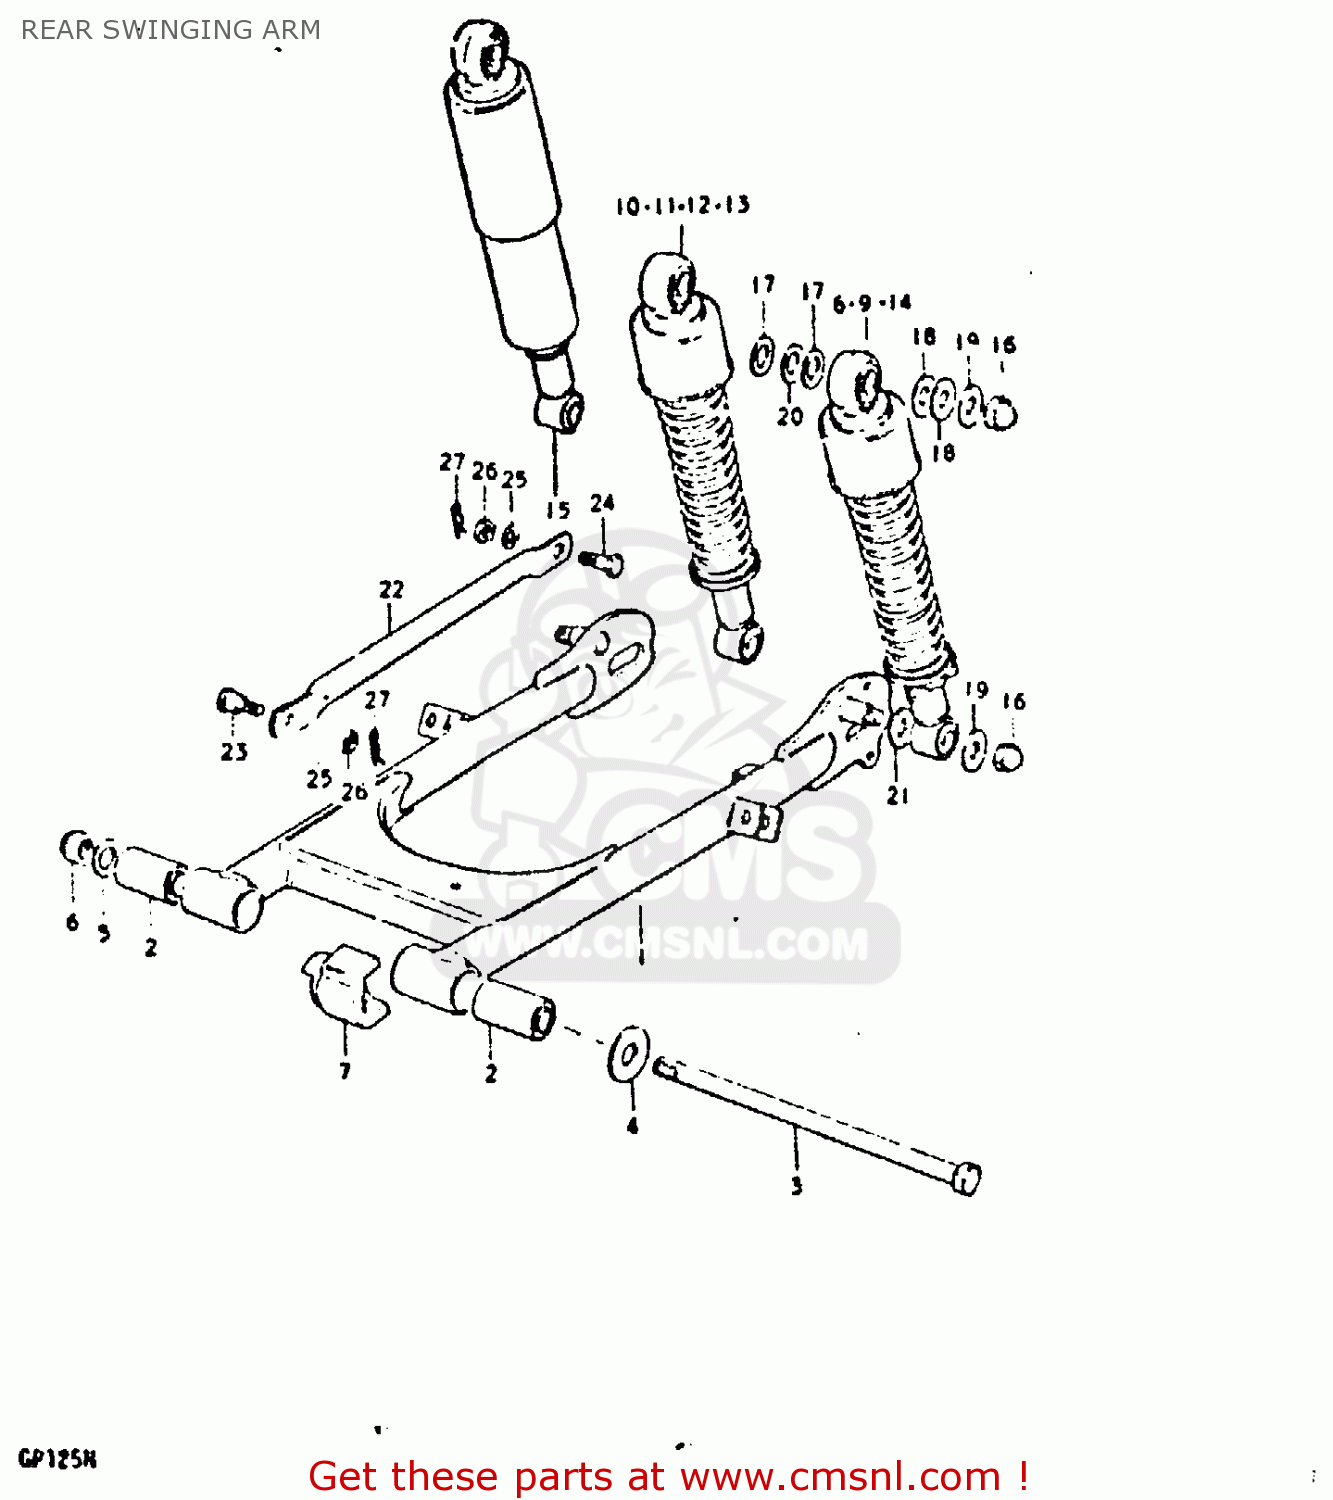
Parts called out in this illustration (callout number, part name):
1	REAR SWINGING ARM SET
2	BUSH(12X24X44)
3	SHAFT,REAR SWING ARM
4	WASHER(12.5X32X2.3)
5	WASHER
6	NUT
7	BUFFER,CHAIN TOUCH DEFENSE
10	11-1
11	16
16	NUT, LOWER LH
17	WASHER
18	WASHER
19	WASHER(10.5X24X3.2)
20	WASHER (12.5X24X3.2)
21	WASHER
22	TORQUE LINK, REAR
23	BOLT(8X22.5)
24	BOLT(8X26.5)
25	LOCK WASHER
26	NUT
27	CLIP
